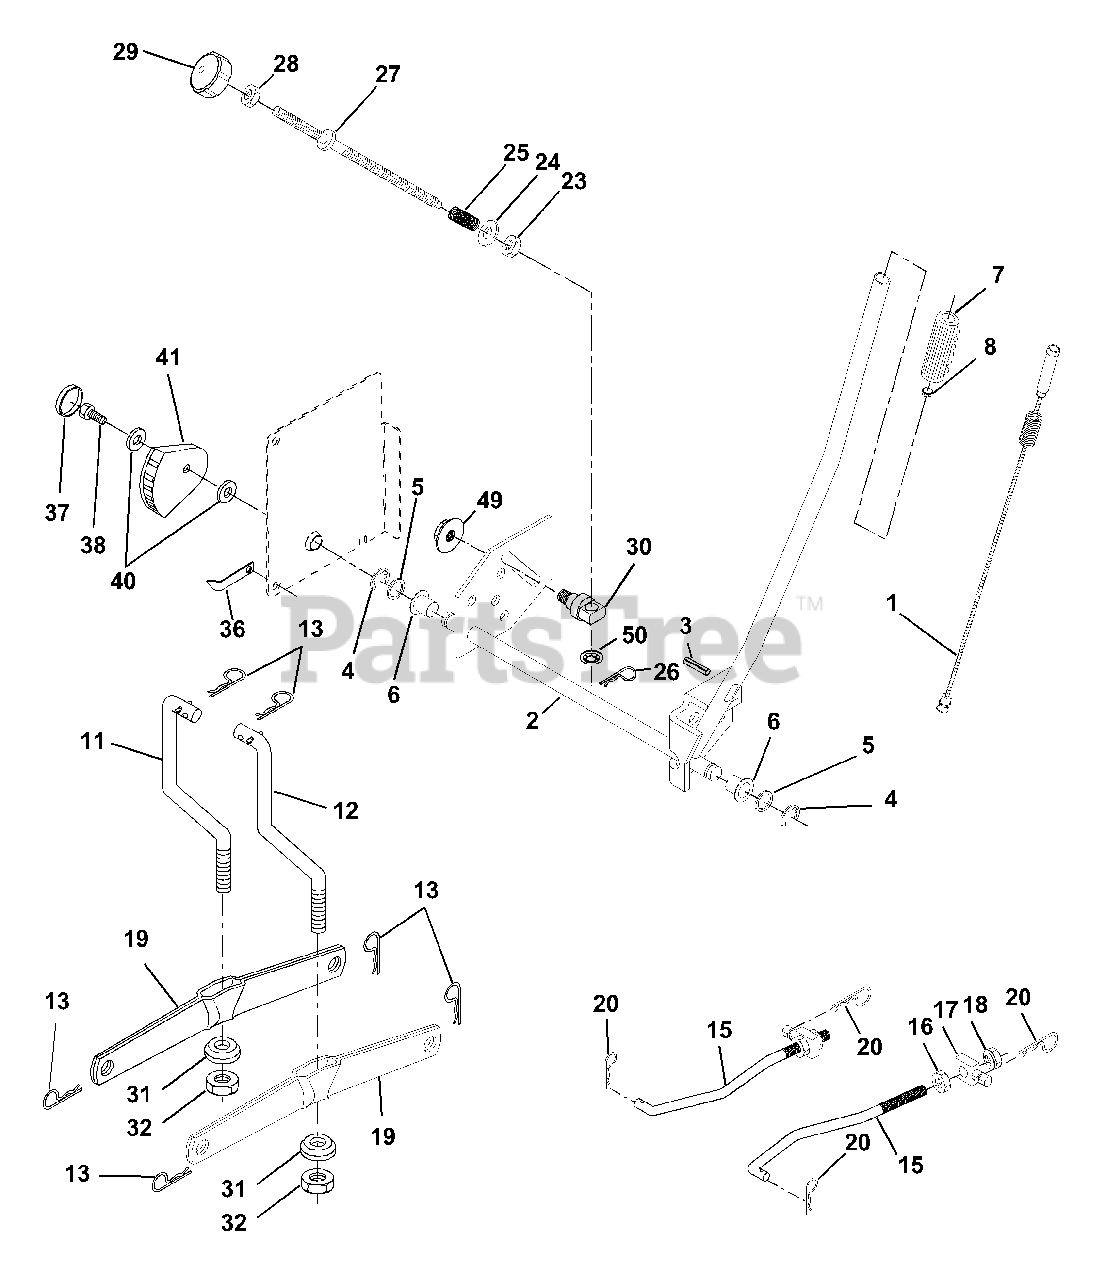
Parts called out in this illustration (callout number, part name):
1	Wire Asm Inner/Spring W/Plunger LT
2	Shaft Asm Lift RH w/Inf
3	Pin Groove 1 500 Zinc
4	E Ring #5133-62
5	Washer 21/32 X 1 X 21 Ga
6	Bearing Nylon Blk 629 Id
7	Grip Handle Fluted Blk
8	Button Plunger Black
11	Link Lift LH Fixed Length
12	Link Lift RH Fixed Length
13	Retainer Spring
15	Link Front
16	Nut Jam Hex 1/2-13 Unc
17	Trunnion Blk Zinc
18	Nut Lock w/Wsh 1/2-13unc
19	Arm Suspension Rear
20	Retainer Spring
23	Nut Special
24	Washer 13/32 X 5/8 X 16 Ga
25	Spring 2-1/8"
26	Retainer Clip
27	Rod Adj Lift Zinc 7.49 Wrk Lg
28	Nut Hex Jam 3/8-16 Unc
29	Knob Inf 3/8-16 Unc Blk W/sym
30	Trunnion Infin Height
31	Bearing Pvt Lift Spherical
32	Nut Crownlock 3/8 - 24
36	Indicator Height STLT
37	Plug Hole Blk 1.485/1.515 Dia.
38	Screw 5/16-18 x 1
40	Washer 11/32 x 1-1/2 10 Ga.
41	Scale Ind. Height Blk.
49	Nut Hex Flange Lock
50	Nut, Push Phos & Oil
